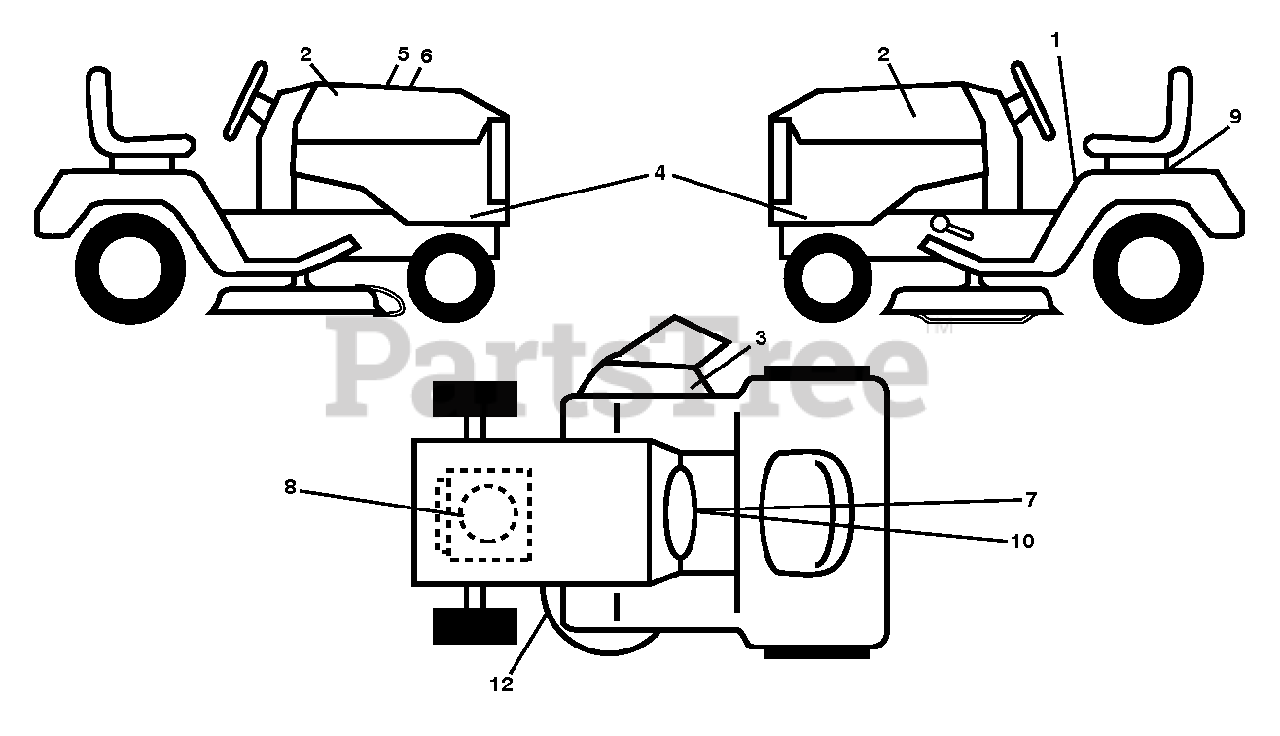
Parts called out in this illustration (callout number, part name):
1	DECAL.FENDER.WARNING.ENGLISH
2	DECAL.BADGE.170MM.TEXTLOGO.
3	DECAL.MOWER.WARN.KEEP.HAND.AWY
4	DECAL.SDPNL.HUSGT2.YTH2042.
5	DECAL.WARNING.CUST.RESP.E85.
7	LABEL.EMISS.CALIF.HUSQVARNA
8	Decal, Engine BS 20HPXRD
9	DECAL BTRY SYMBOLS
10	DECAL, WARNING SPARK ARRESTOR
12	DECAL.V-BELT.SCH.42/46"MEC/ELE
